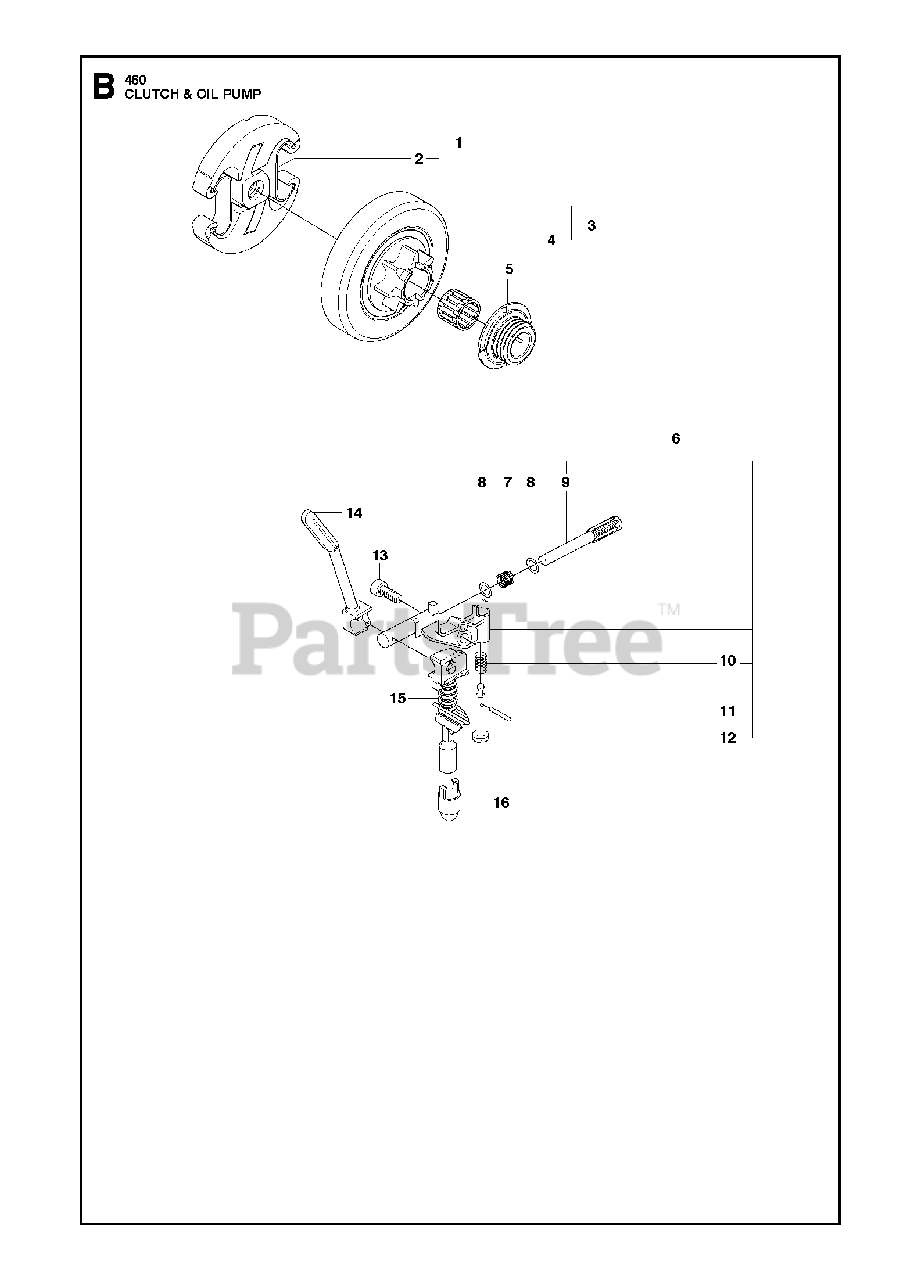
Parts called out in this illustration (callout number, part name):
2	SPRING
3	CLUTCH DRUM
4	NEEDLE BEARING
5	GEAR WORM OILER
6	OIL PUMP ASSY
7	SPRING
8	WASHER
9	PUMP PISTON
10	SPRING
11	PIN
12	ADJUSTER
15	OIL HOSE
16	OIL SCREEN
